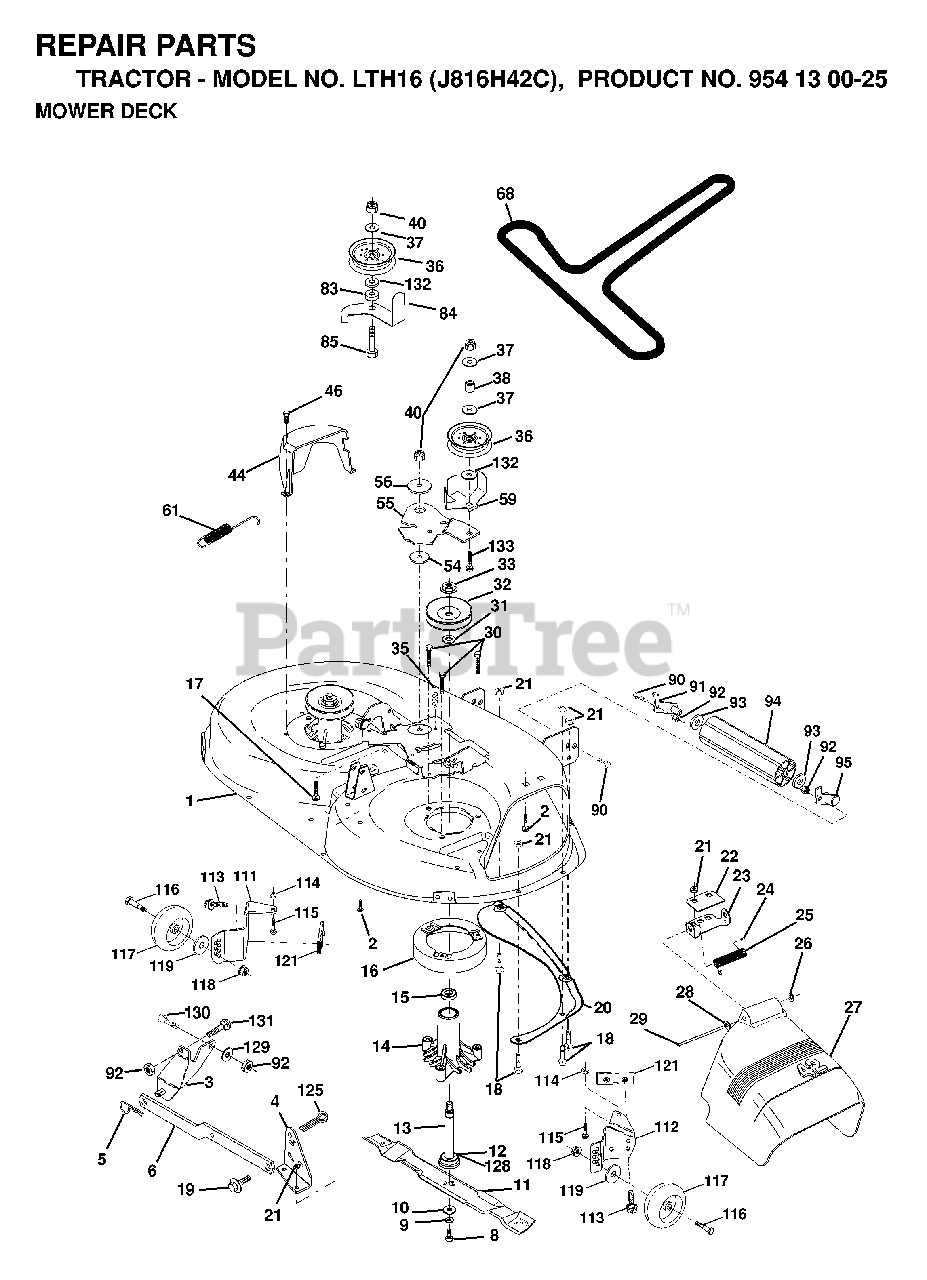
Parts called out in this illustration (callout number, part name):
1	DECK 42"
2	BOLT
3	BRKT ASM SWAY BAR
4	BRKT DECK SW BAR
5	RETAINER-SPRNG RB
6	REAR SUSP ARM
8	BLADE BOLT
9	LOCKWASHER
10	WASHER.BLADE
12	BEARING
13	SHAFT ASM VENT
14	HSG MANDREL
16	STRIPPER
17	BOLT CARRIAGE
18	BOLT
19	BOLT SHD 5/16-18
20	BAFFLE.VORTEX
21	LOCKNUT
22	STIFFENER BRACKET
23	DEFLECTOR BRACKET
24	CAP-SLEEVE LT
25	SPRING TORSION
26	NUT PUSH M
27	SHIELD.DEFLECTOR.MOWER.42".BLK
28	WASHER
29	ROD.HINGE
30	SCREW THDROL ROLLING WASHER HD
31	WASHER
32	PULLEY/MANDREL
33	NUT
35	FASTENER.XMAS.TREE
36	FLAT IDLER PULLEY
38	IDLER SPRING SPACER
40	LOCKNUT
44	GUARD MANDREL LH BLACK
46	SCREW.1/4-20X5/8
54	HARDENED WASHER
55	IDLER ARM
56	SPACER RETAINER
59	GUARD, BELT
61	SPRING EXTENSION
83	BOLT
84	KEEPER.BELT.IDLER
90	BOLT
91	BRACKET LH (A)
92	NUT
94	NOSE ROLLER
95	BRACKET RH (B)
111	BRACKET WHEEL GAUGE LH 42" DK
112	BRACKET WHEEL GAUGE RH 42" DK
113	SCREW
114	NUT
115	BOLT
118	LOCKNUT
119	WASHER
121	BRACKET.EXTRD.GWL
125	COTTER PIN
128	WASHER FELT
129	WASHER
131	BOLT D
132	WASHER GT
